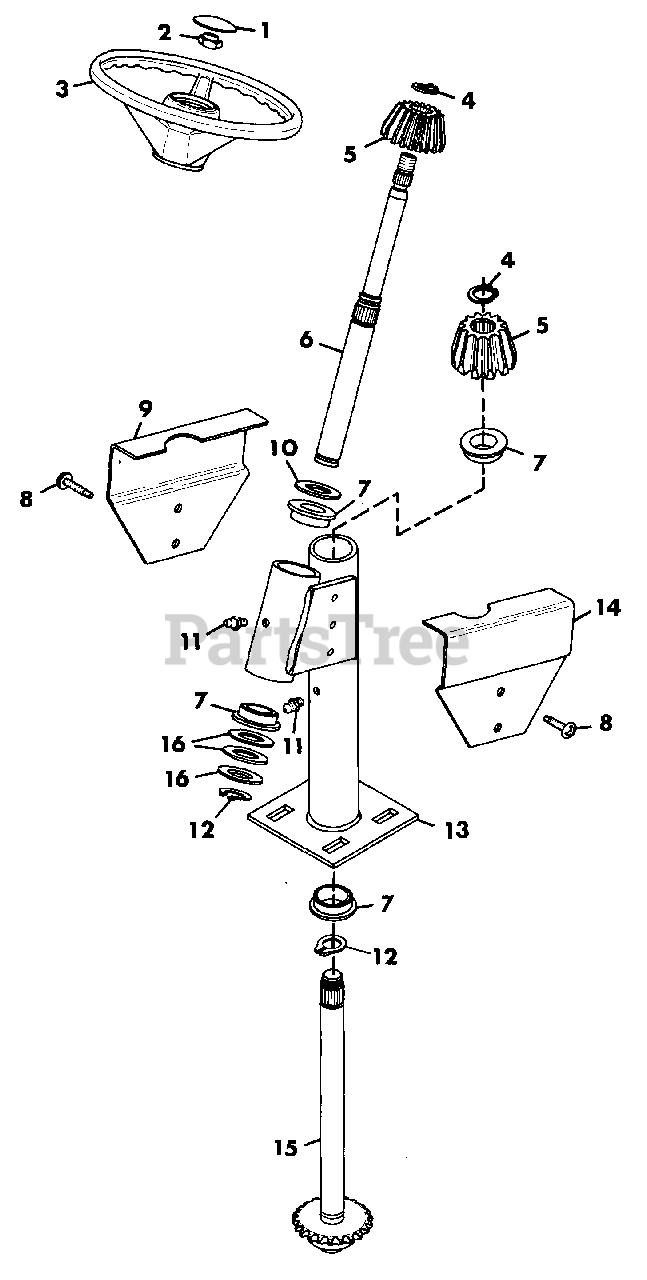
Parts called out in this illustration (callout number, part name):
1	CAP, STEERING WHEEL
2	NUT, LOCK 5/8-11
3	WHEEL, STEERING
4	RING, RETAINING .875 SHAFT
5	PINION, BEVEL
6	SHAFT, STEERING WHEEL
7	BEARING, FLANGED
8	SCREW, TAPPING 10-24X.50
9	GUARD, STEERING
10	BEARING, THRUST RACE
11	FITTING, LUBE 1/4-28
12	RING, RETAINING
13	TUBE, STEERING
14	GUARD, STEERING
15	WELDMENT, STEERING SHAFT
16	RACE, BEARING THRUST
